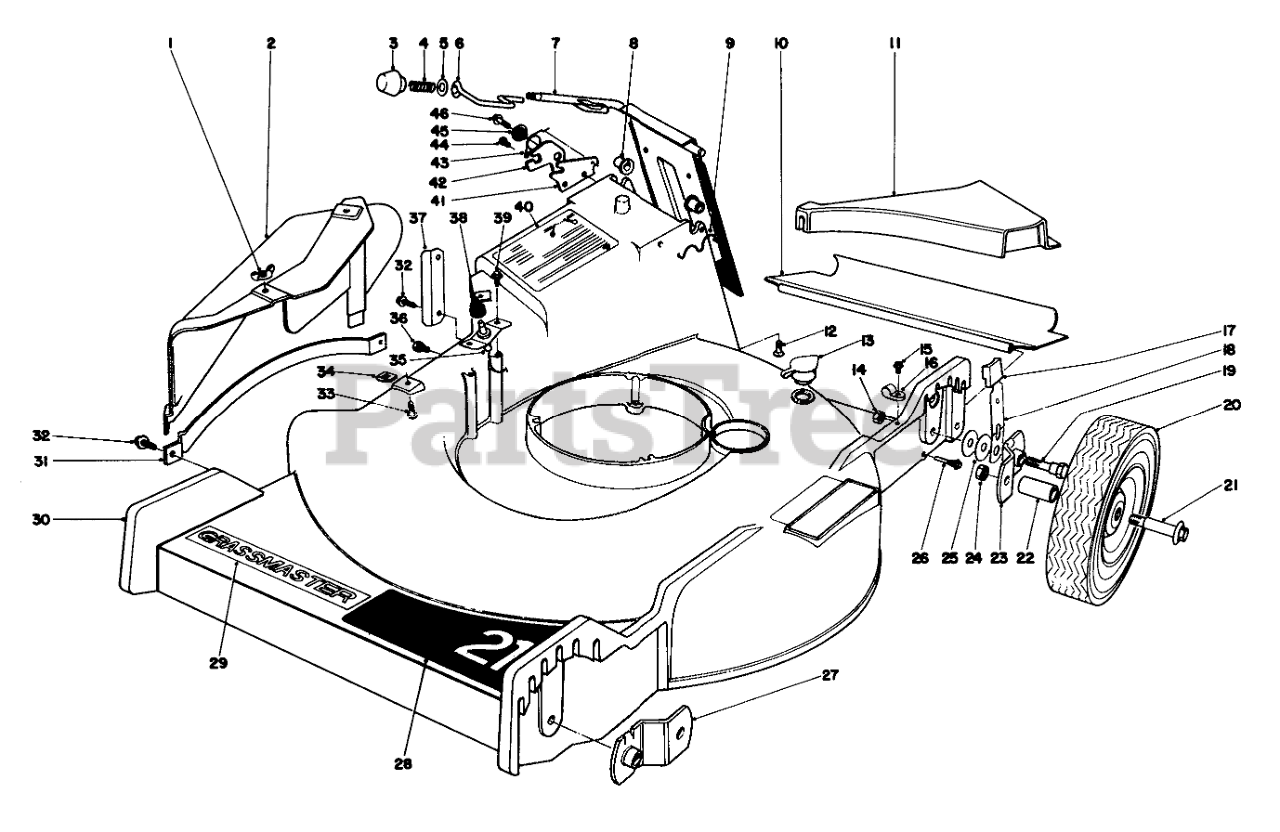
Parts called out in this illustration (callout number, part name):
1	NUT-WING SPECL
2	DEFLECTOR
4	COMPRESSION SPRING
5	WASHER
6	DOOR LATCH
7	Door Handle
8	BUSHING-NYLON
9	Door Retainer
10	REAR SAFETY SHIELD
11	REAR INSERT
12	SCREW-HH
13	WASHOUT PLUG
14	Nut
15	SCREW
16	CABLE CLAMP
17	Knob
18	SPRING ARM ASM
19	PIVOT SCREW
20	Wheel & Tire (Incl. Ref. #22)
22	Bushing
23	PIVOT ARM ASM A
24	Nut
25	WASHER-PIVOT
26	SAFTEY SHIELD SCREW
27	PIVOT ARM ASM B
28	Decal
29	Decal Grassmaster
30	Housing
31	Bar Safety
32	SCREW
35	Deflector Switch (Incl. Ref. #38)
36	SCREW THD 1/4 20 5/8
37	Clip Retaining
38	Boot Switch
40	Decal-Caution
41	DOOR LATCH PLATE
42	Latch Safety
43	TORSION SPRING
44	SCREW-HWH
45	Latch Spacer
46	Screw
